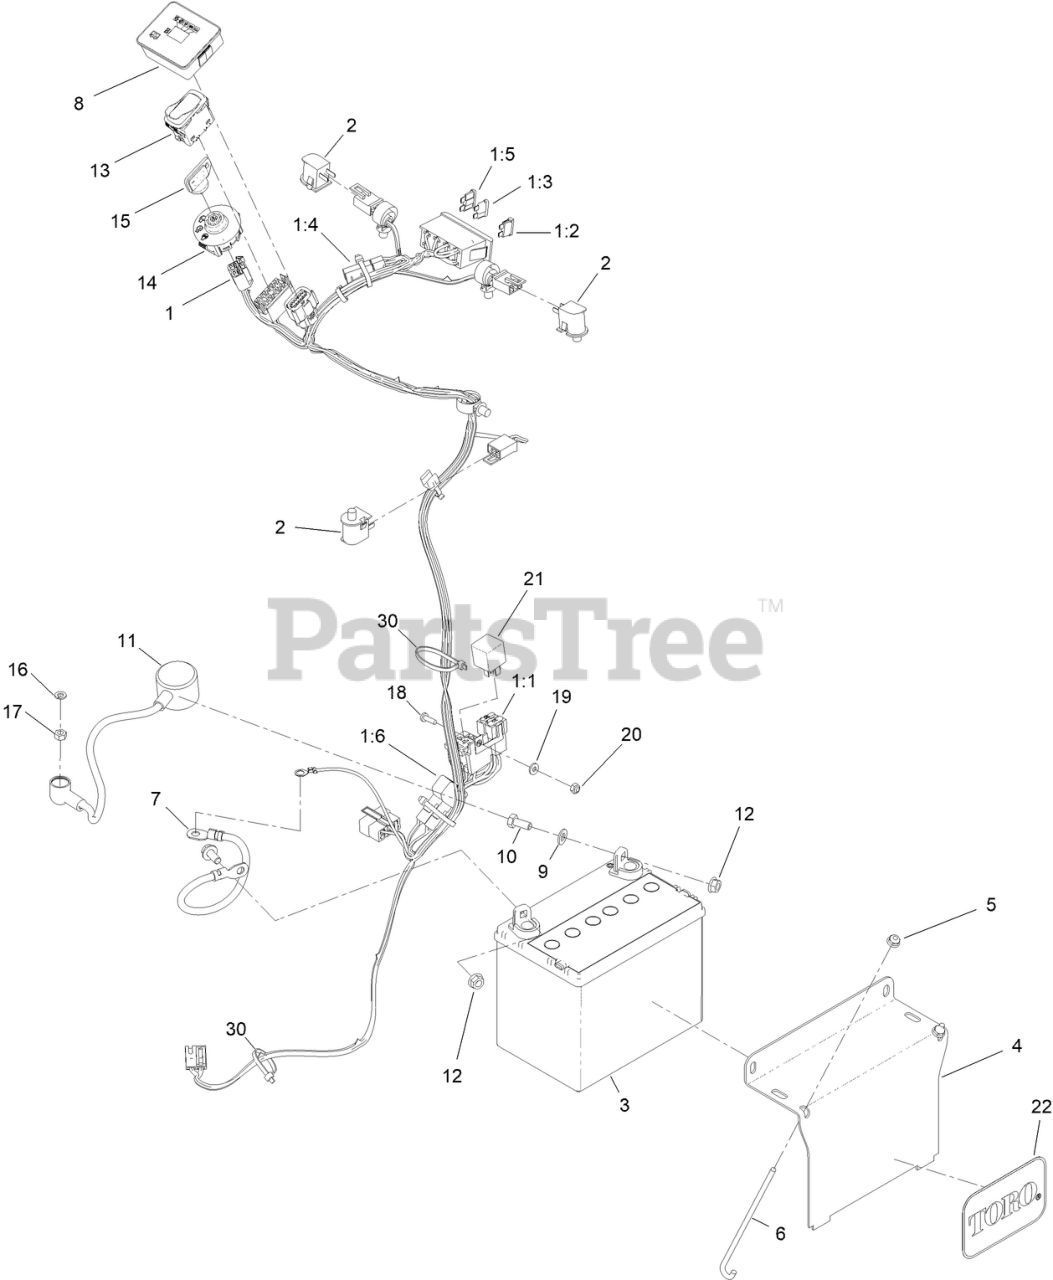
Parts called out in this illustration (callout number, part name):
1	HARNESS-WIRE, GRANDSTAND
1:1	FUSE-BLADE, 20 AMP
1:2	FUSE-BLADE, 15 AMP
1:3	FUSE-BLADE, 10 AMP
1:4	CAP-PLUG
1:5	FUSE-BLADE, 5 AMP
1:6	FUSE-BLADE, 30 AMP
2	SWITCH-BAIL
3	BATTERY-DRY
4	BRACKET-HOLD DOWN, BATTERY
5	NUT-HF
6	BOLT-HOLDDOWN
7	CABLE-BATTERY, BLACK
8	MODULE-METER, HOUR
9	WASHER-PLAIN
10	SCREW-HH
11	CABLE-BATTERY, POSITIVE
12	NUT-HHF, SMOOTH
13	SWITCH-ROCKER, (ON)-ON-OFF
14	SWITCH-IGNITION
15	KEY-IGNITION
16	WASHER-LOCK
17	NUT-HEX
18	SCREW-PPH
19	WASHER-FLAT
20	NUT-LOCK, NI
22	DECAL
30	TIE-CABLE
